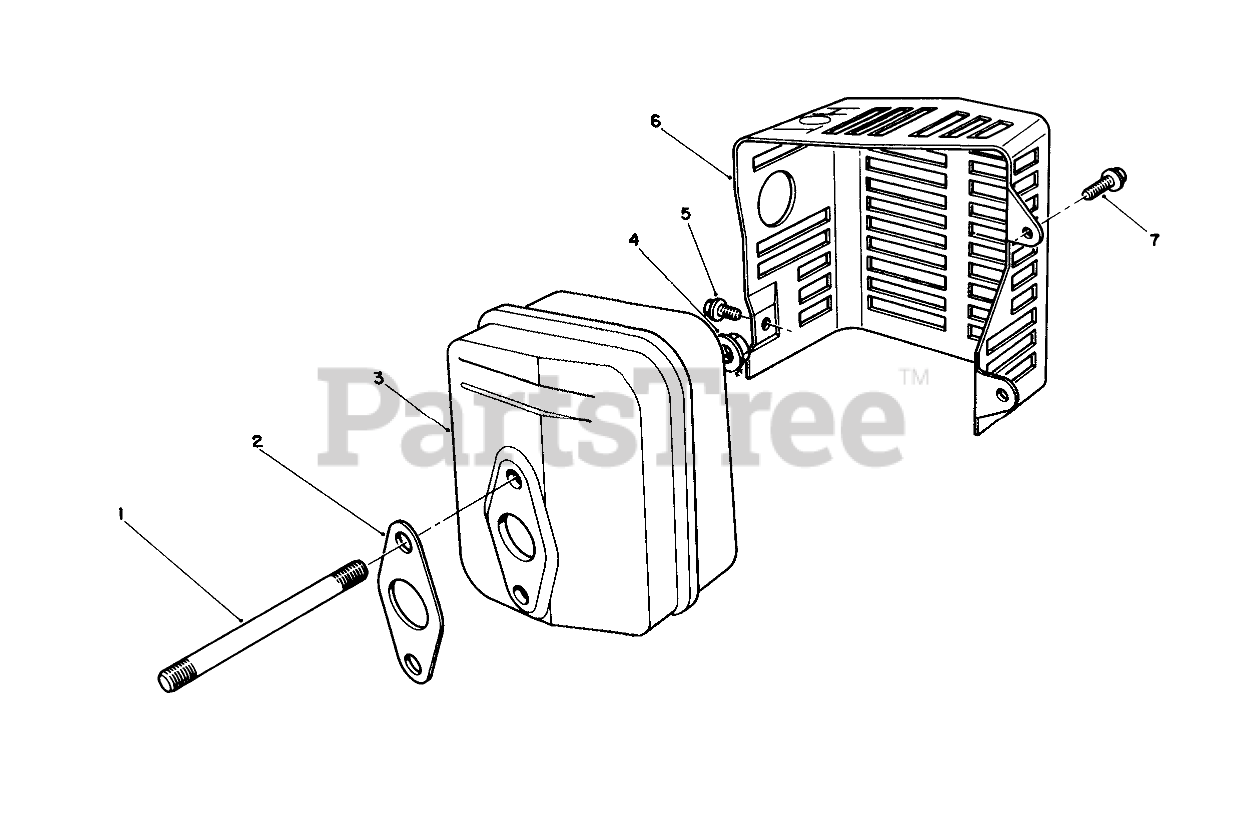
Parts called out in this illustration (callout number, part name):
2	GASKET
3	MUFFLER
5	SCREW
6	COVER
